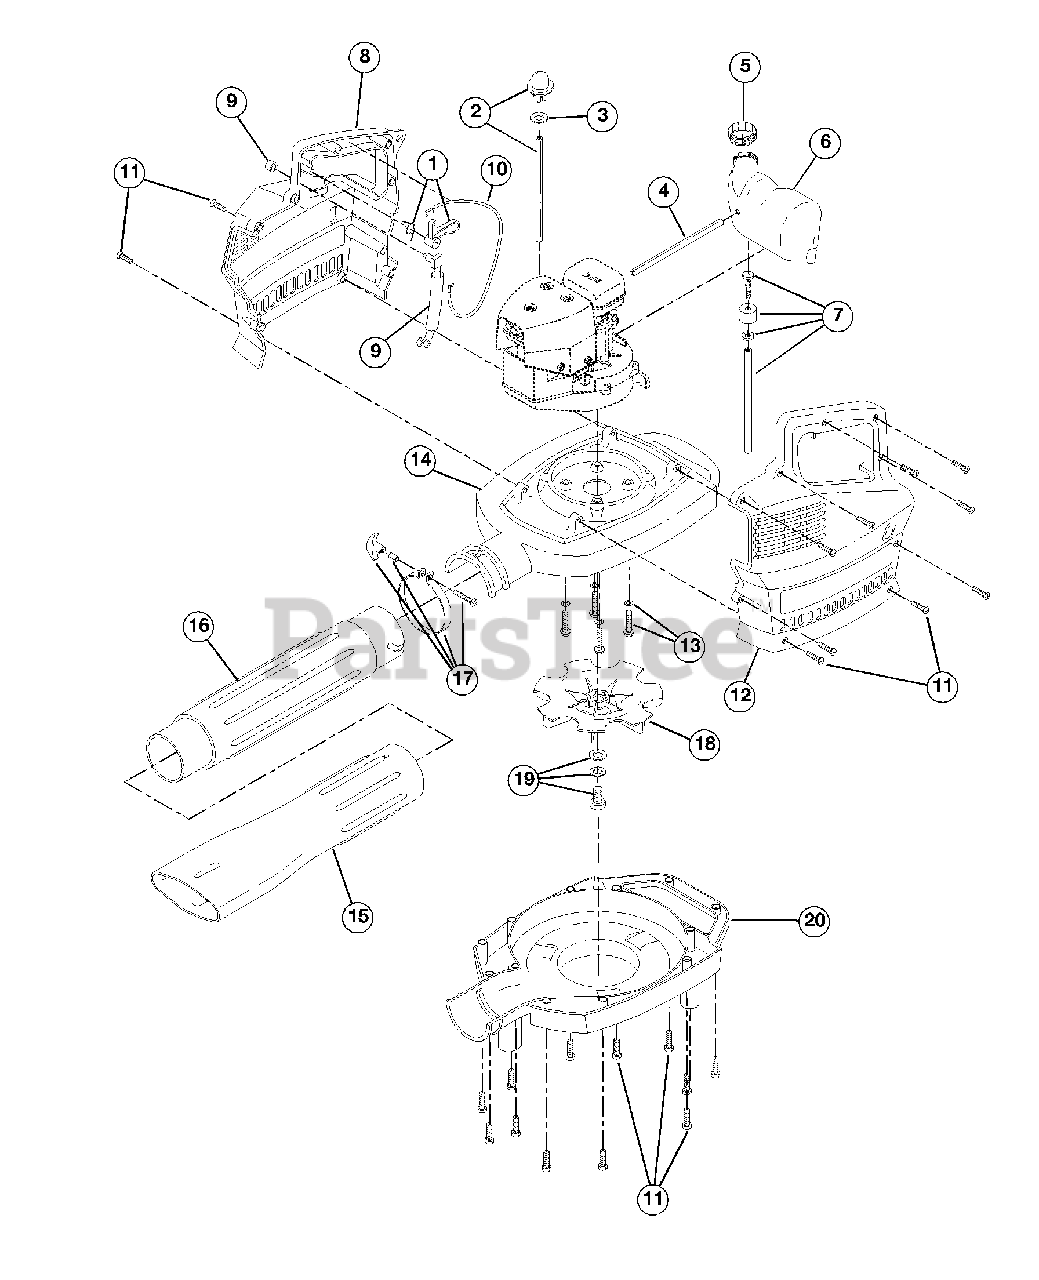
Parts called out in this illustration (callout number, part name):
1	Trigger Assembly
2	Primer Bulb and Hose Assembly
3	Primer Washer
4	Return Line
5	Fuel Cap Assembly
6	Complete Fuel Tank Assembly
7	Fuel Line Assembly
8	R.H. Engine Cover
9	Switch and Lead Assembly
10	Throttle Wire and Housing Assembly
11	Mounting Screw
12	L.H. Engine Cover
13	Mounting Screw Assembly
14	Upper Blower Housing
15	Blower Tube W/Nozzle
16	Blower Tube
17	Clamp Assembly
18	Impeller
19	Mounting Bolt Assembly
20	Lower Blower Housing W/Door
